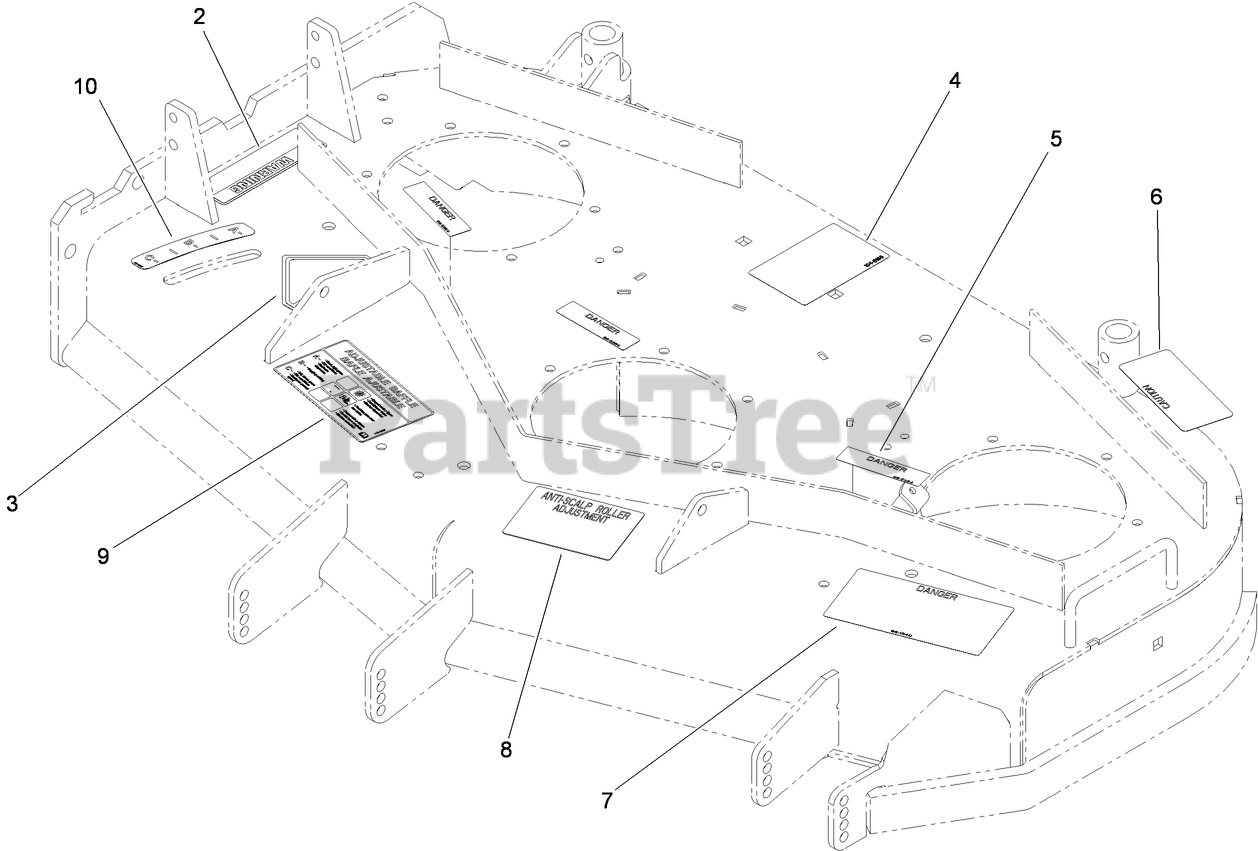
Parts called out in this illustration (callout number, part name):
2	DECAL-WARNING
3	DECAL-DANGER
4	DECAL-ROUTING, BELT
5	DECAL-COVER, MISSING
6	DECAL-TORQUE
7	DECAL-DANGER, THROWN OBJECT
8	DECAL-SCALP, ANTI
9	DECAL-ADJUSTMENT, BAFFLE
10	DECAL-SETTING, BAFFLE
